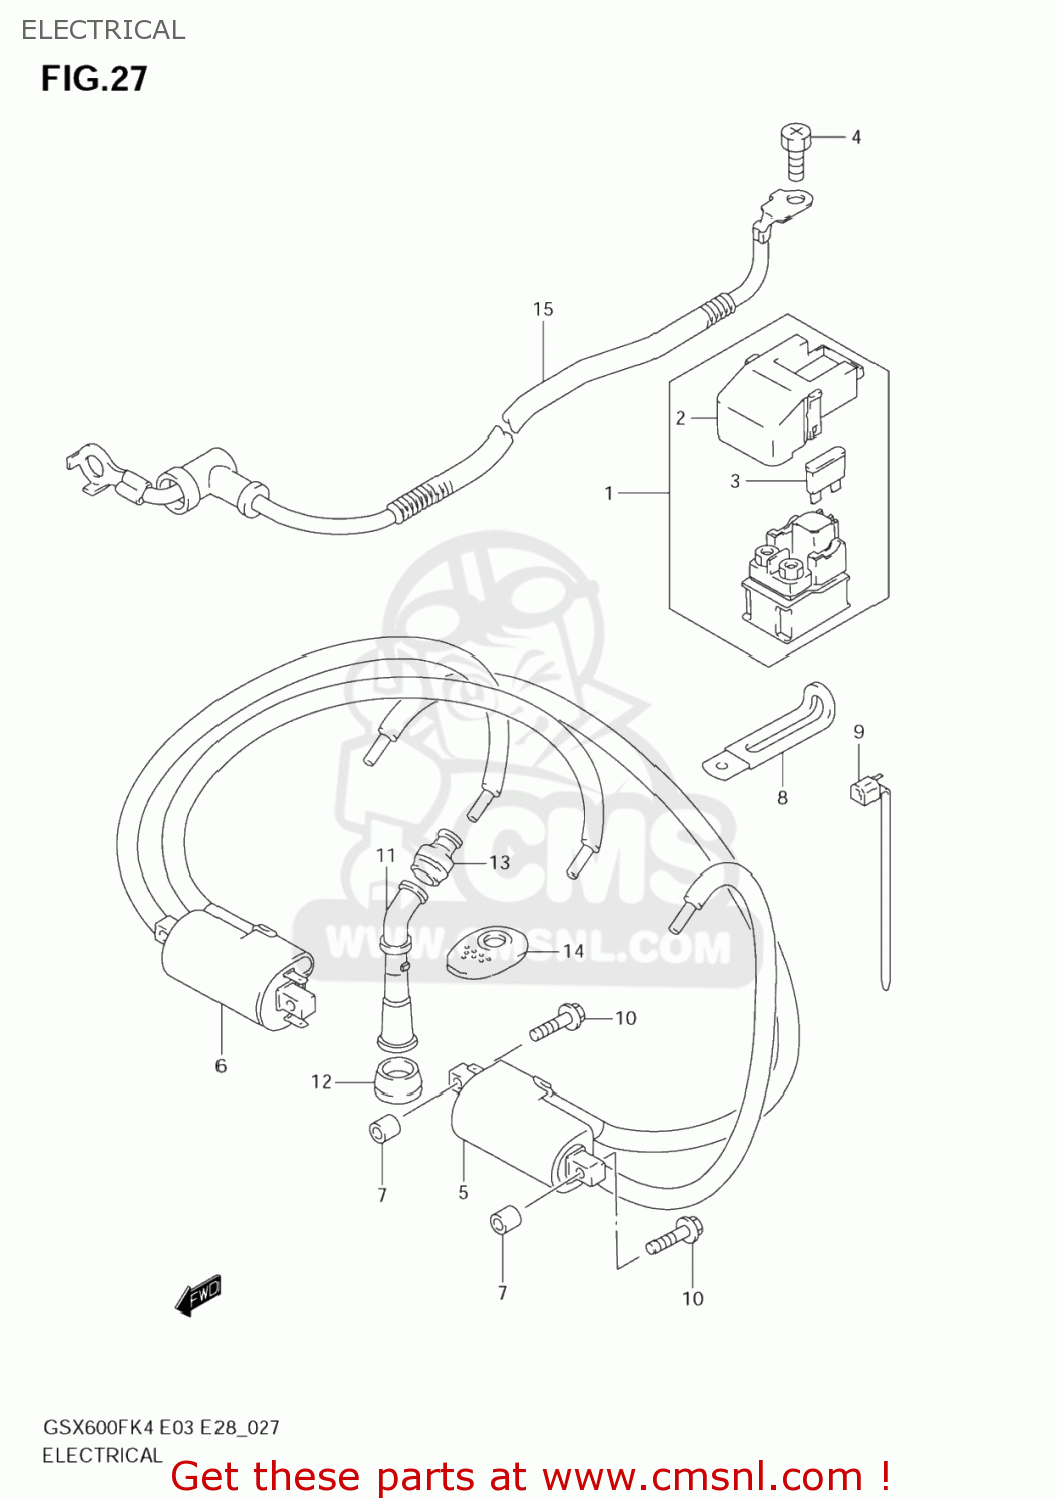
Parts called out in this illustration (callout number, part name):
1	RELAY ASSY,STARTING MOTOR
2	COVER
3	FUSE(30A)
4	SCREW(6X8)
5	COIL ASSY,IGNITION
6	COIL ASSY,IGNITION
7	SPACER(6.2X12X14)
8	CLAMP(L:80)
9	CLAMP(L:165)
10	BOLT (6X45)
11	CAP,SPARK PLUG
12	SEAL,SPARK PLUG CAP
13	SEAL,HIGH TENSION CORD
14	COVER,SPARK PLUG CAP
15	WIRE,BATTERY MINUS
